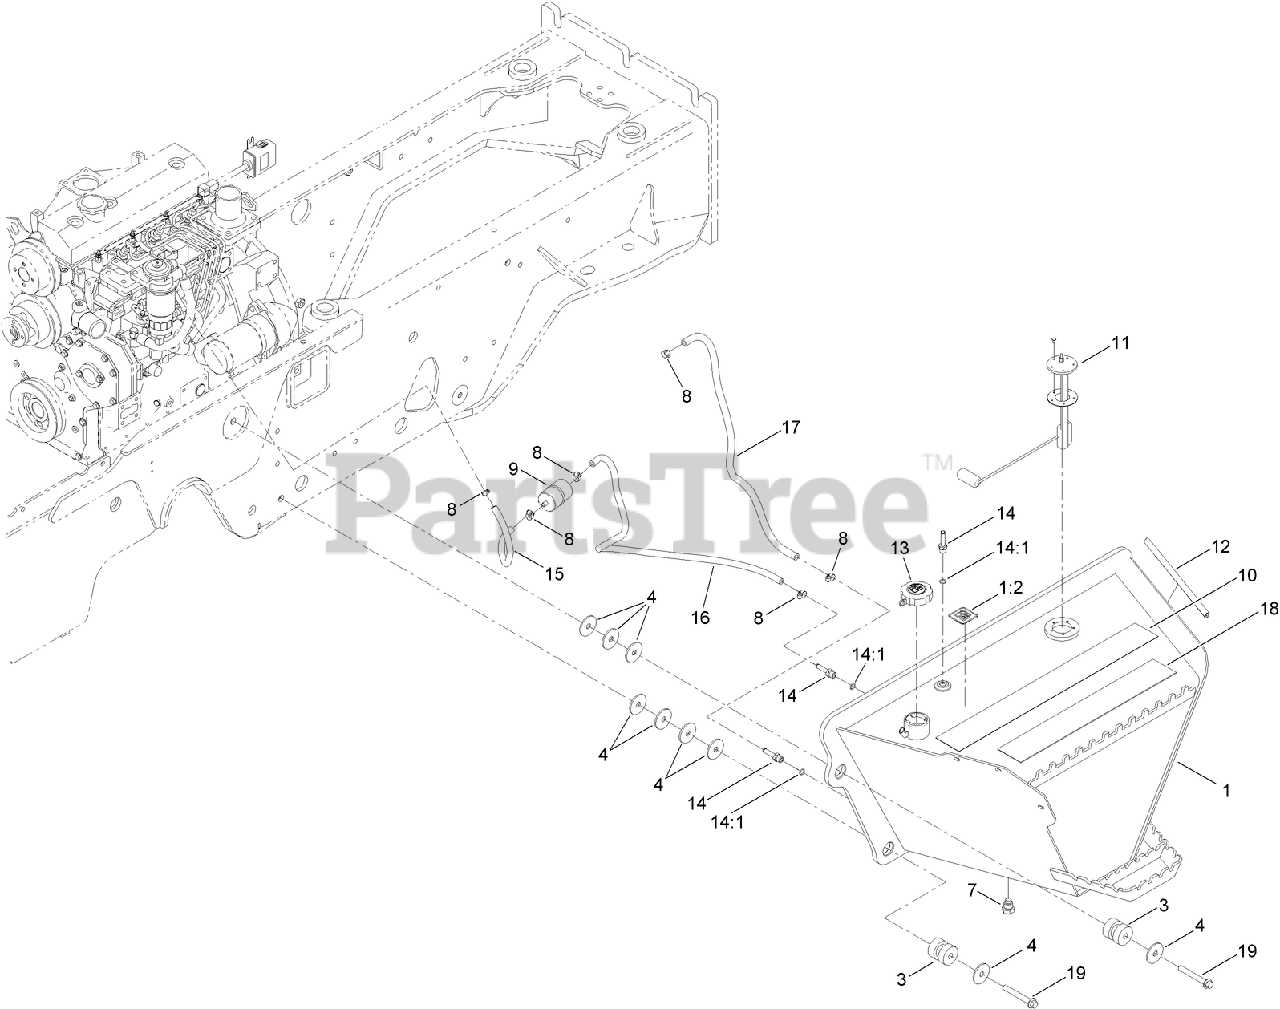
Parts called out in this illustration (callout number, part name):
1	FUEL TANK ASM
1:2	DECAL-DIESEL
3	ISOLATOR-MOUNTING, UNIVERSAL
4	WASHER-FLAT
7	PLUG-HEX, MAGNETIC
8	CLAMP-WORM
9	FILTER-INLINE FUEL
10	STRIP-ANTI SKID
11	SENDER-FUEL LEVEL
12	STRIP-SEAL
13	CAP-DIESEL FUEL, NON-VENTED
14	FITTING-STR
14:1	O-RING
15	HOSE-FUEL
16	HOSE-FUEL
17	HOSE-FUEL
18	TAPE-ANTI SKID, LOWER STEP
19	SCREW-HHF
